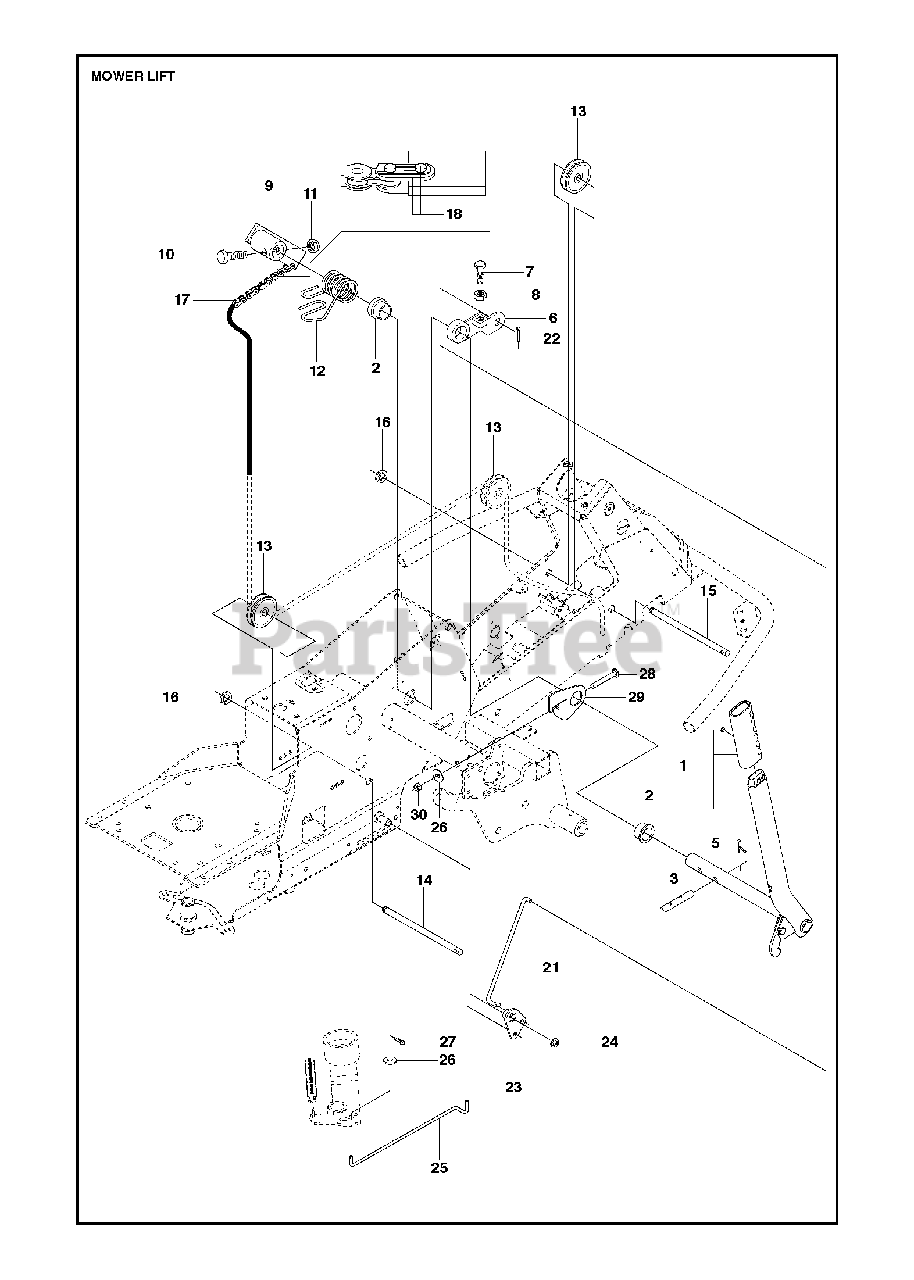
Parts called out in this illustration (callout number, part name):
1	LIFTING LEVER ASSY
2	BEARING FLANGE
6	LEVER CLUTCH
8	NUT
9	LIFTING ARM
11	Lock Nut, Fiber M12 DIN 985 Z/P
21	CONNECTION ROD
24	RETAINING RING
25	CONNECTION ROD
30	LOCKNUT M8
